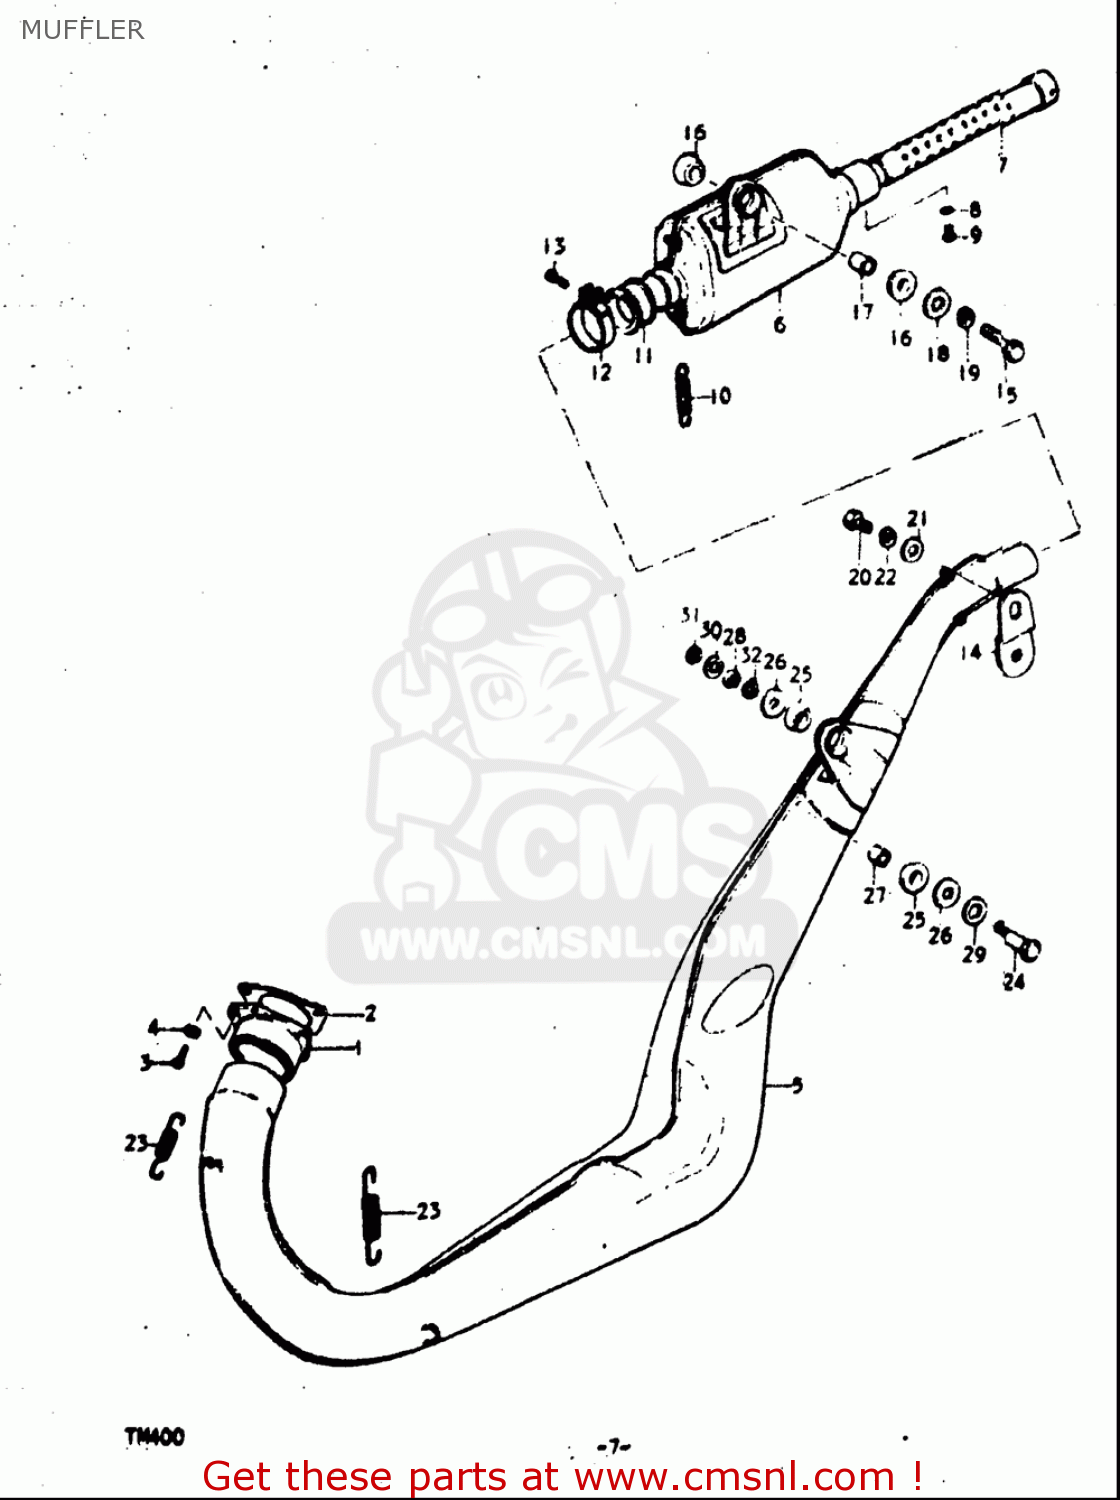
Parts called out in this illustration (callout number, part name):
3	SCREW
4	WASHER,LOCK
8	WASHER,LOCK
9	SCREW(6X8)
10	SPRING
13	SCREW
14	BRACE,MUFFLER
15	BOLT
17	SPACER (8.2X12.5X23.5)
18	WASHER(8.5X22X2)
19	WASHER,LOCK
20	BOLT
21	WASHER
22	WASHER,LOCK
23	SPRING
26	WASHER(8.5X22X2)
27	SPACER (8.2X12.5X23.5)
29	WASHER
30	WASHER
31	E RING
32	WASHER,LOCK
